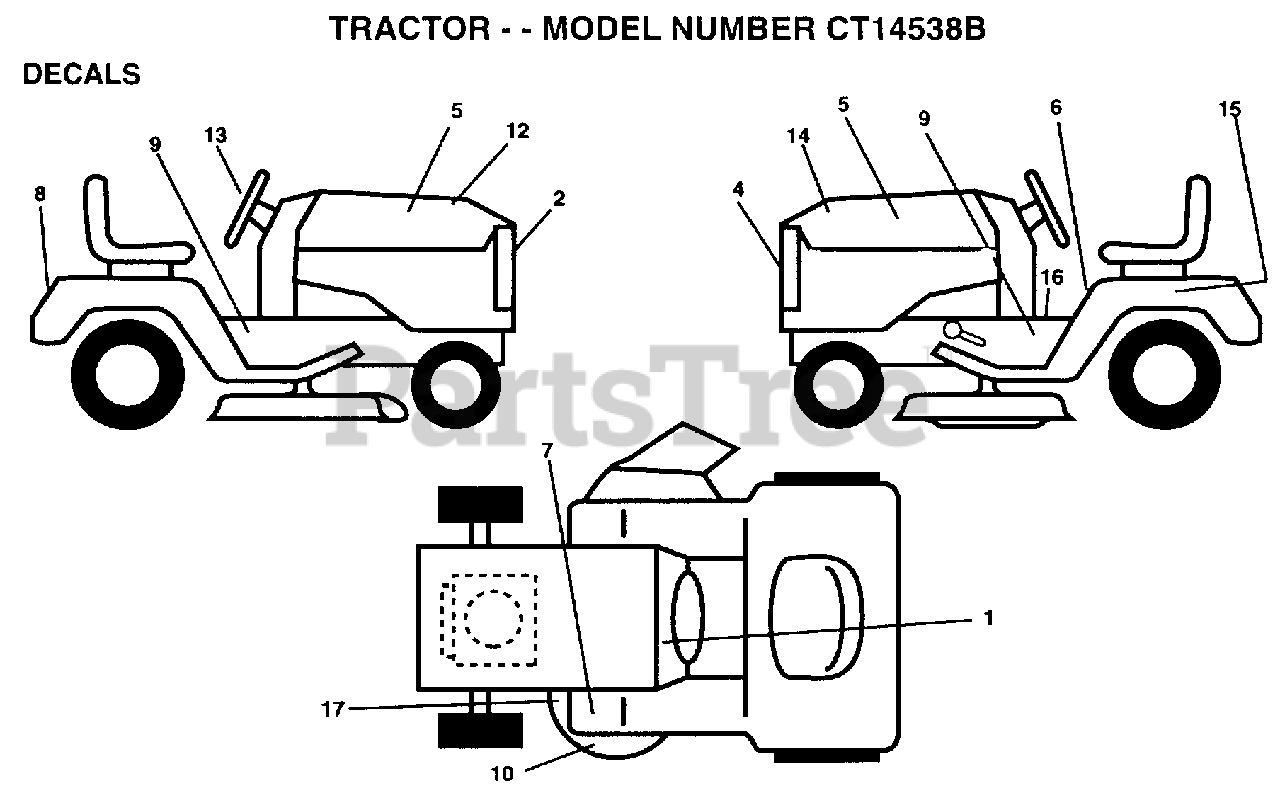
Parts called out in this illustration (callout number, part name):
1	DECAL.DASH.INST.
2	GRILL DECAL
5	DECAL.INS.HD.RALL
6	DECAL
8	FENDER DECAL
12	DECAL HOOD RH RLY
13	"DECAL,STR WHL"
14	DECAL HOOD LH RLY
15	DECAL.BTRY.DANGER
16	DECAL BRAK PARK
17	DECAL
